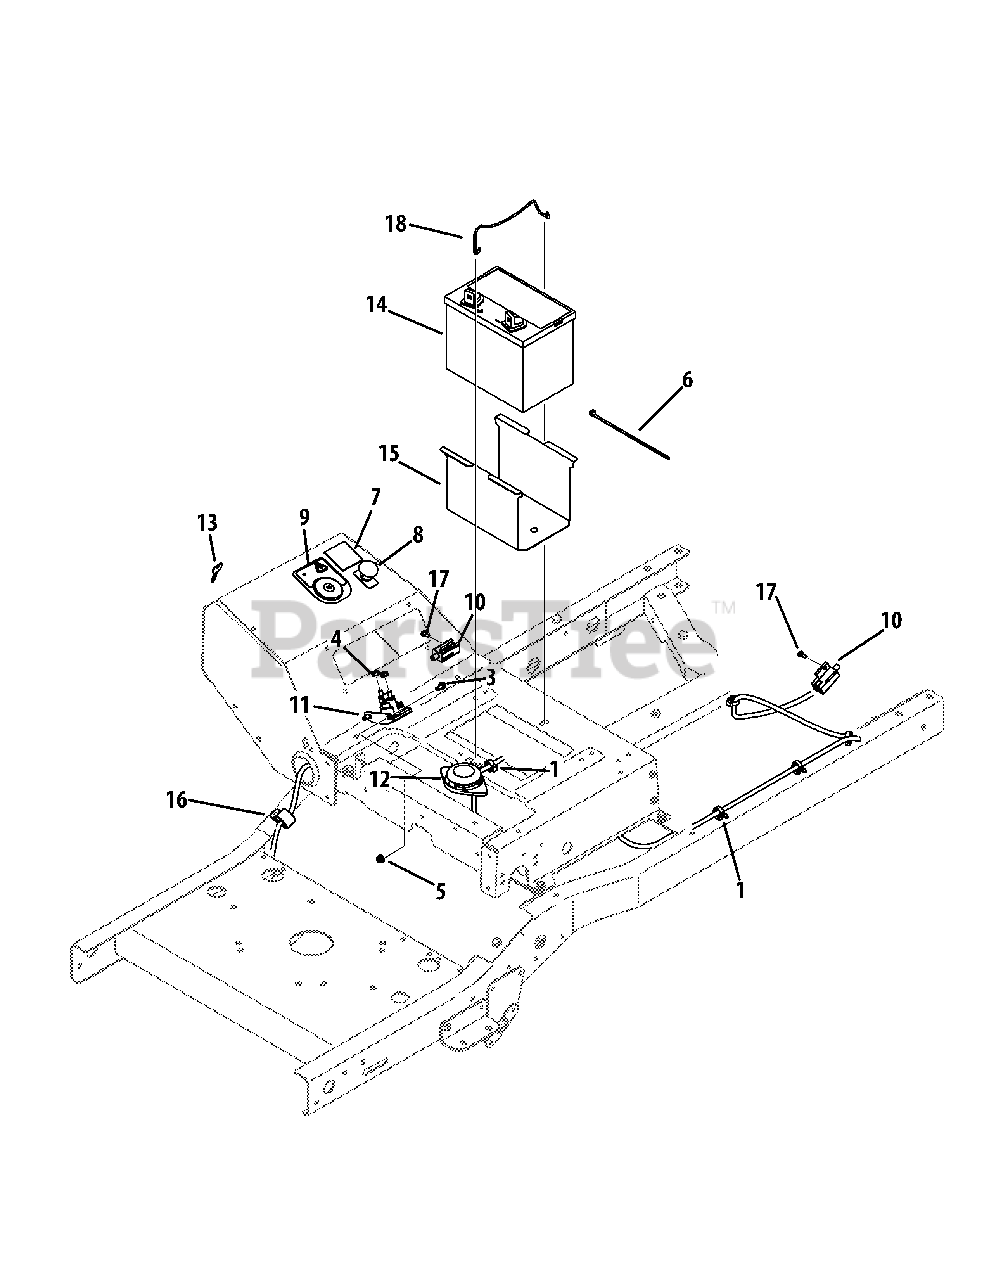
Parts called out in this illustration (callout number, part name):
1	Electrical Conduit Clip, 1/2
3	Hex Washer Screw, 1/4-20 x 0.500
4	Sems Nut, 1/4-20
5	Flange Lock Nut, 1/4-20
6	Cable Tie, 3/16 x .05 x 7.4
7	Hour Meter/Service Minder
8	Electric PTO Switch
9	Key Switch
10	Interlock Switch
11	Solenoid
12	Seat Switch Assembly
13	Universal Key
13	Universal Key with hang tag
13	Cub Cadet Key
16	Clamp, 1.0
17	Shoulder Screw, #10-32 x .500
18	Battery Rod
